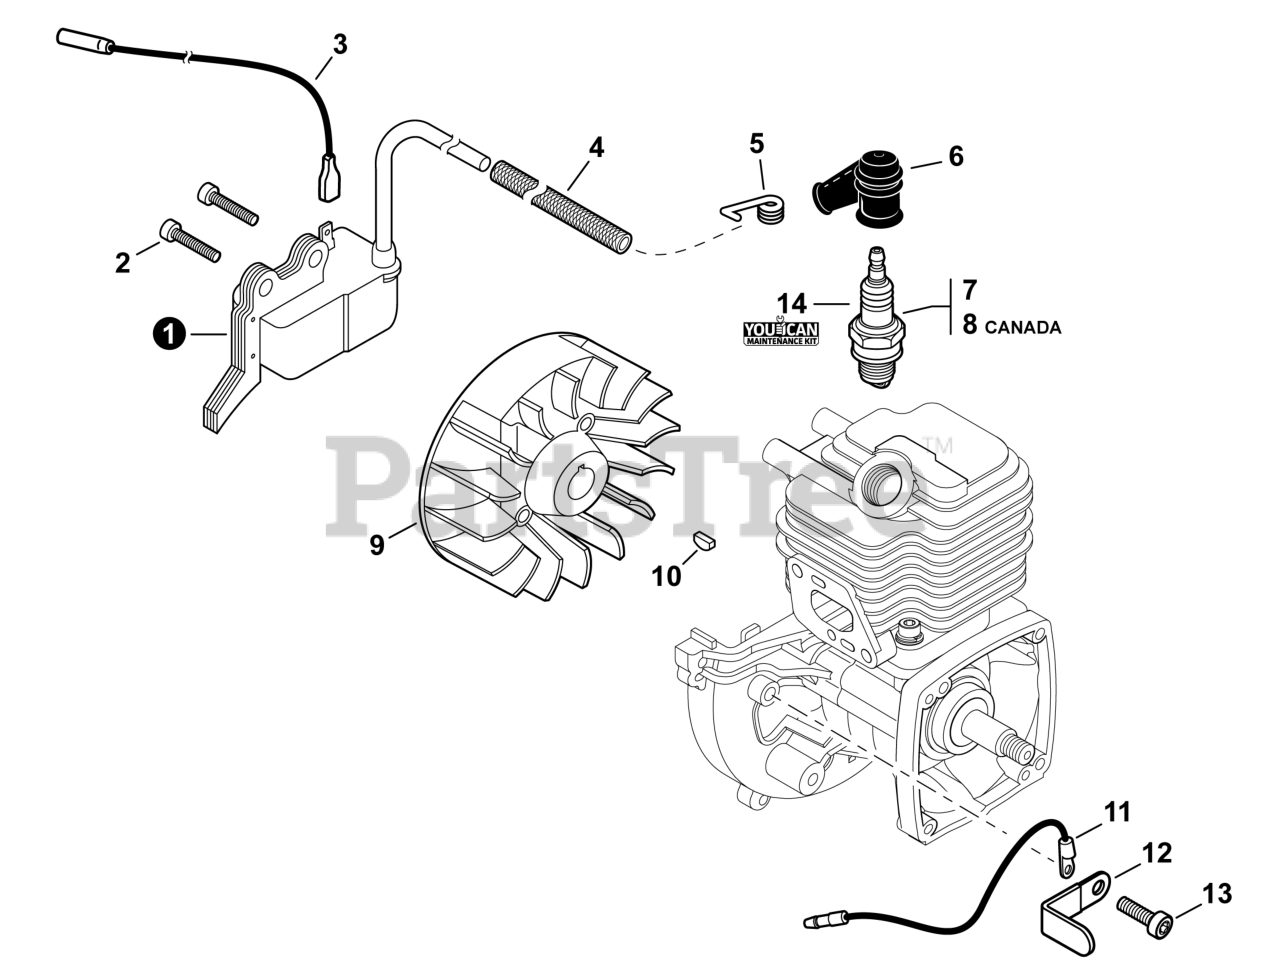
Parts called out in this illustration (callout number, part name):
1	COIL, IGNITION
2	BOLT, TORX 4×20
3	LEAD - IGNITION L= 210
4	TUBE, INSULATOR
5	TERMINAL, SPARK PLUG
6	CAP, SPARK PLUG
7	SPARK PLUG - BPM8Y
8	SPARK PLUG - BPMR8Y
9	FLYWHEEL
10	KEY, WOODRUFF
11	LEAD - GROUND L= 115
13	BOLT, TORX 5×10
14	TUNE-UP KIT - YOUCANT
